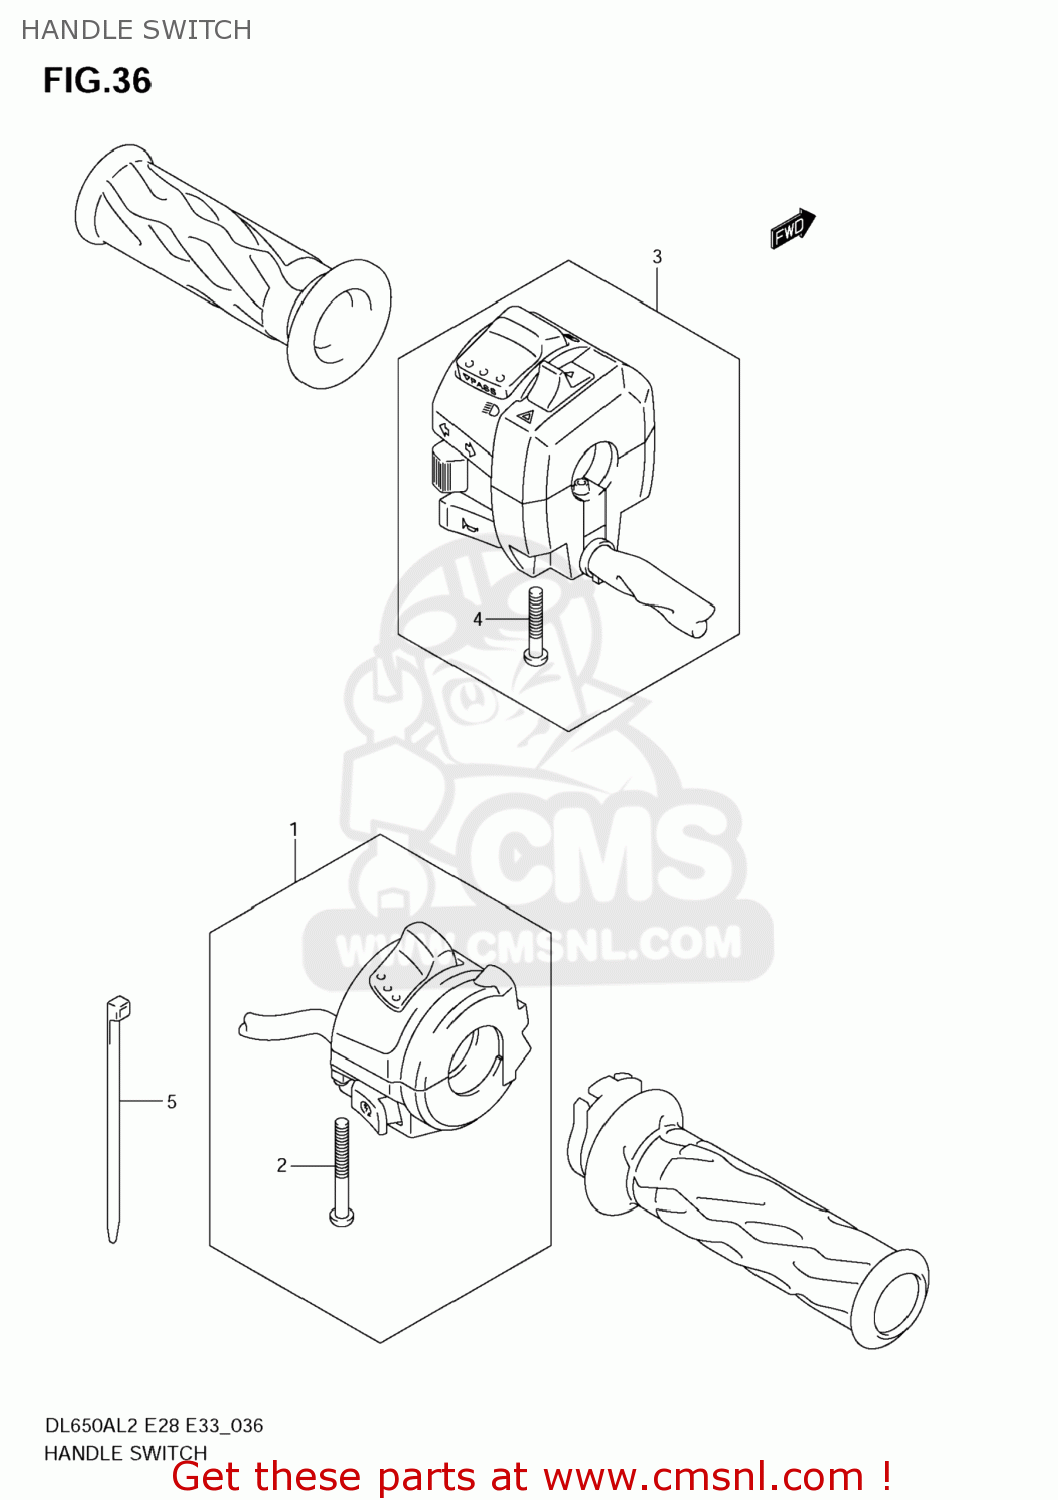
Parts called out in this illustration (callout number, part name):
1	SWITCH ASSY,HANDLE,R
2	SCREW
3	SWITCH ASSY,HANDLE,L
4	SCREW
5	CLAMP(L:145)
